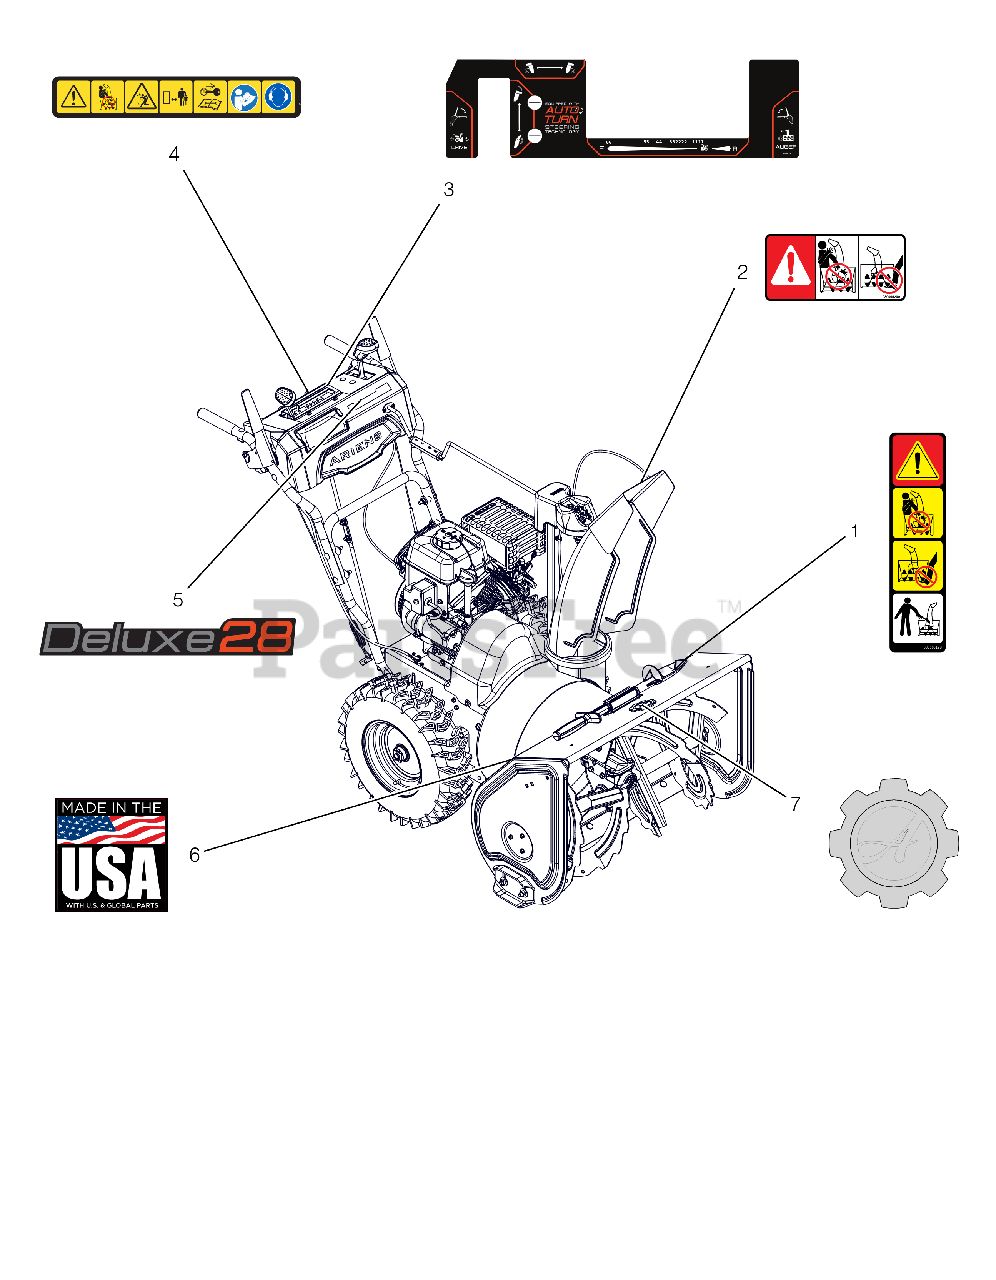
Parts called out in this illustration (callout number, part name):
1	DECAL, DANGER - ROTATING PARTS
2	DECAL, DANGER
3	DECAL,CONTROL-SML,AT,ID
4	DECAL,DASH - SAFETY
5	DECAL, DASH - DELUXE 28
6	DECAL, MADE IN USA
7	DECAL, ARIENS-GEAR BADGE -THK
